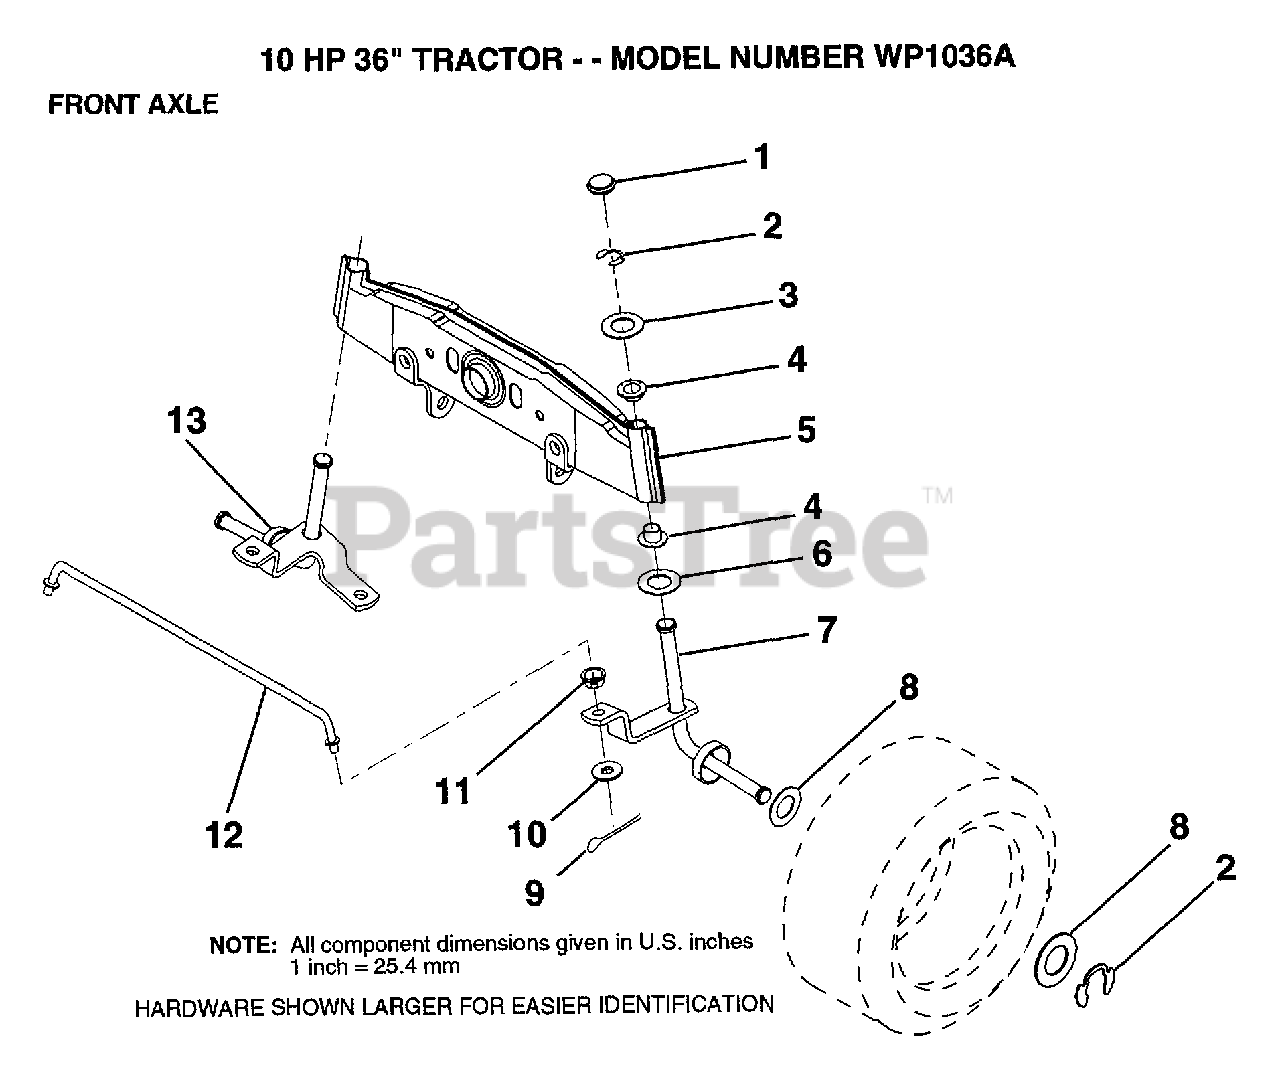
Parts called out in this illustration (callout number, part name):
1	CAP
2	RING
3	WASHER
4	NYLINER
5	AXLE FRONT
6	WASHER .T
7	SPINDLE RH
8	WASHER
9	COTTER PIN
10	WASHER
11	BUSHING.DRAGLINK
12	ROD TIE
13	SPINDLE LH
